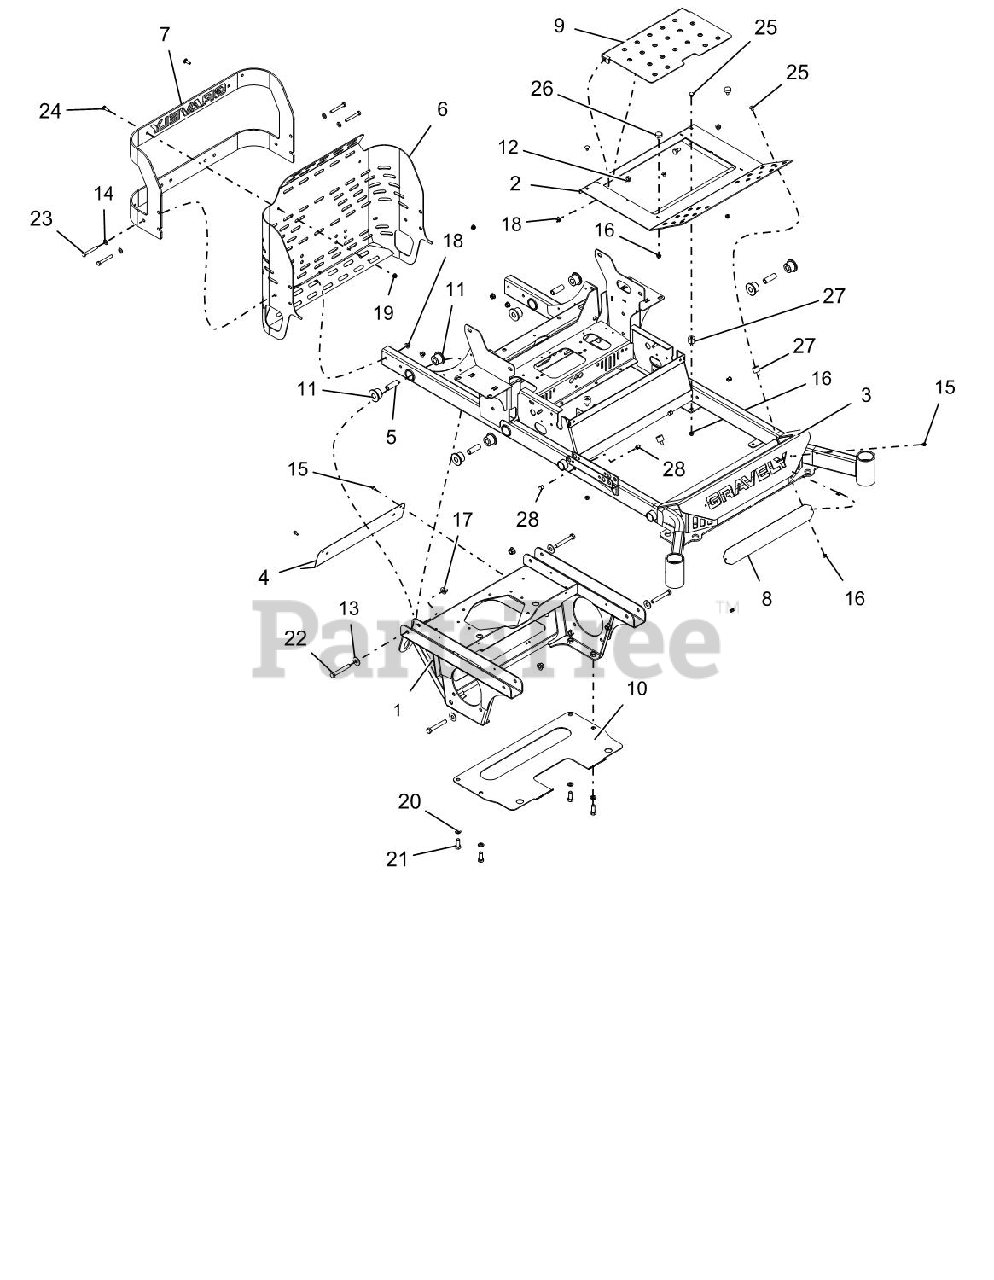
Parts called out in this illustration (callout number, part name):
1	PT200/400 AXLE/ENG FRM WMT-RED
2	FOOTPLATE WLDMT W/SAFETY DECAL
3	52-66"PT400 MAIN FRAME WMT-RED
4	MUFFLER HEAT SHIELD - BLACK
5	BSHG-SLV .50X.75X2.23
6	WLDMT, PT400 REAR BUMPER
7	REAR BUMPER W/SAFETY DECAL-GAS
8	BUMPER LOGO BACKING PLATE -BLK
9	INSPECTION PANEL W/SAFTY DECAL
10	PLATE-TRANSMISSION SKID
11	BSHG-FLG .75X1.51X1.13X2.0 URE
12	BLT,SHLDR EP .38-16X.30 HEX YZ
13	WSHR-FL-STL.563X1.38X.109YWZC
14	WSHR-FL-STL.406X.812X.065 YWZ
15	SCR-TAP .25-20X.50 HWH TR YWZ
16	NUT-SPNLK-FLG .312-18 YWZC
17	NUT-LK-NYL-FLG .50-13 YWZC
18	NUT-LK-NYL-FLG .38-16 YWZC
19	NUT-LK-NYL-FLG .31-18 YWZC
20	WSHR-LK .50X.125 REG YWZC
21	BLT-HEX .50-13X1.25 GR5 YWZC
22	BLT-HEX .50-13X3.50 GR5 YWZC
23	BLT-HEX .38-16X2.75 GR5 YWZC
24	BLT-RHDSSQNK .31-18X1.00 G5YZ
25	BLT-RDHDSQNK .31-18X.50 G5YZ
26	BUMPER, RUBBER
27	BUMPER,STUD MNTD W/FEMALE INSR
28	PLUG, HOLE .50
